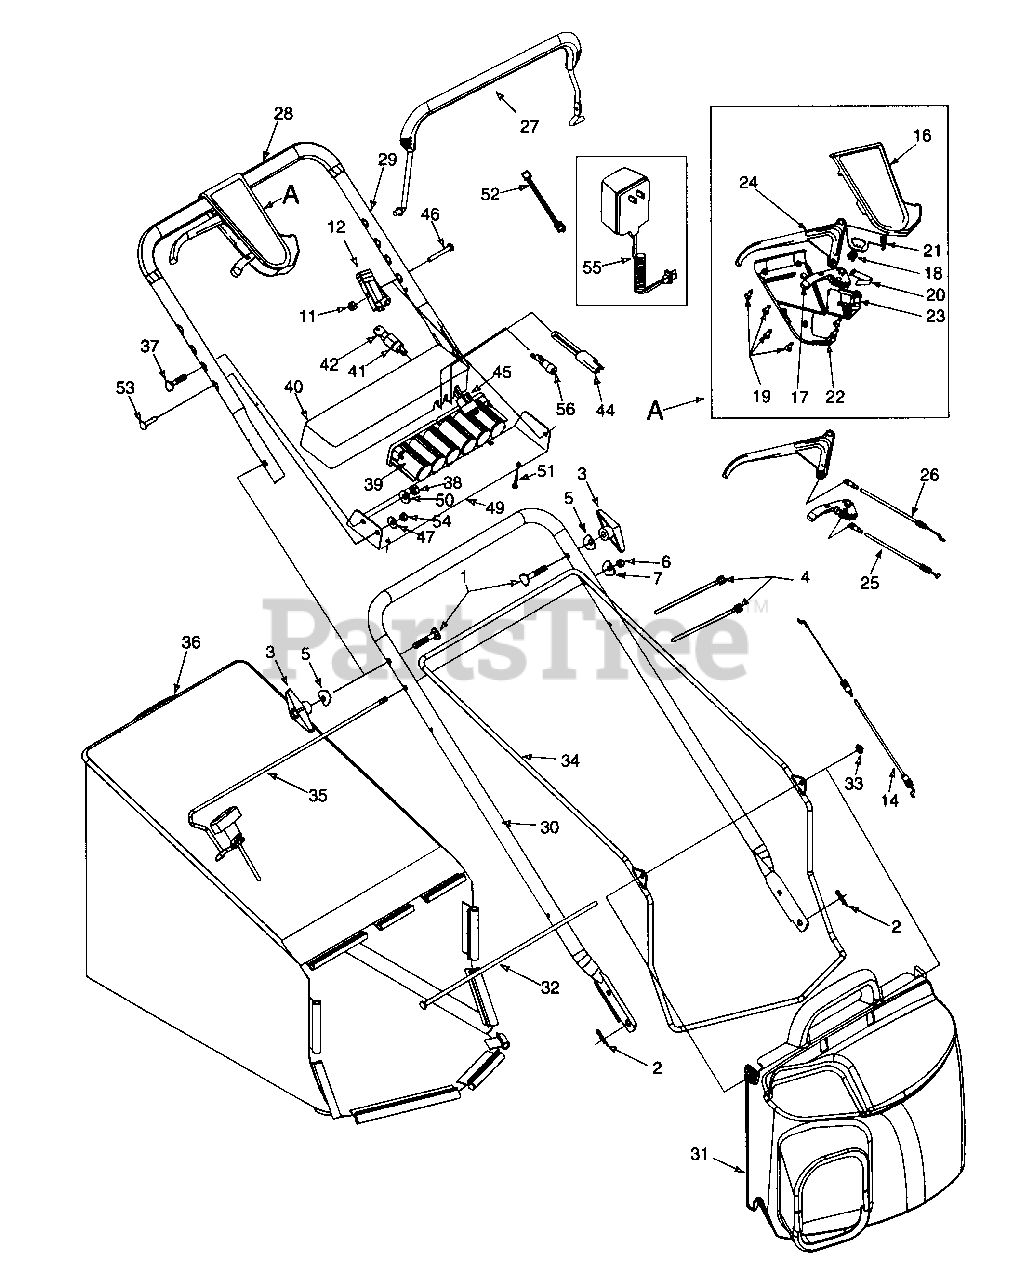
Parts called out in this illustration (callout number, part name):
1	Carriage Bolt 5/16-18 x 2.0
2	Cotter Pin .072 x 1.12 Lg.
3	Knob Assembly 5/16-18
4	Strap 4.3" Lg.
5	Saddle Washer.320 ID x.830 OD
6	Handle Knob 1/4-20
7	Saddle Washer
11	Lock Nut 1/4-20
12	Control Cable Housing
14	Control Cable 44" Lg.
16	Upper Control Housing
17	6-Speed Shift Lever
18	Gear Insert
19	C Sunk Tap Screw #10-16 x .625
20	Shift Lever Spring
21	6 Speed Rack Cable Brkt.
22	Lower Control Housing
23	Cable Mounting Cap
24	Control Lever
25	6 Speed Cable
26	Drive Cable, 52"
27	Control Handle
28	Foam Grip (2 Req'd.)
31	Grass Bag Cover
32	Pivot Rod
36	Grass Bag
37	Carriage Bolt 5/16-18 x 1" Lg.
38	Hex Nut 5/16-18
39	Battery Pack - 12 Volt
40	Battery Tray
41	Ignition Switch
42	Ignition Key
44	Plug
45	Wire Harness
46	Hex Bolt 1/4-20 x 1.3" Lg.
47	Bell Washer 1/4" I.D.
51	Tap Screw 1"
52	Harness Ext.
53	Screw 1/4-20 x 1.25
54	Hex Nut 1/4-20
55	Battery Charger
56	Fuse Holder
